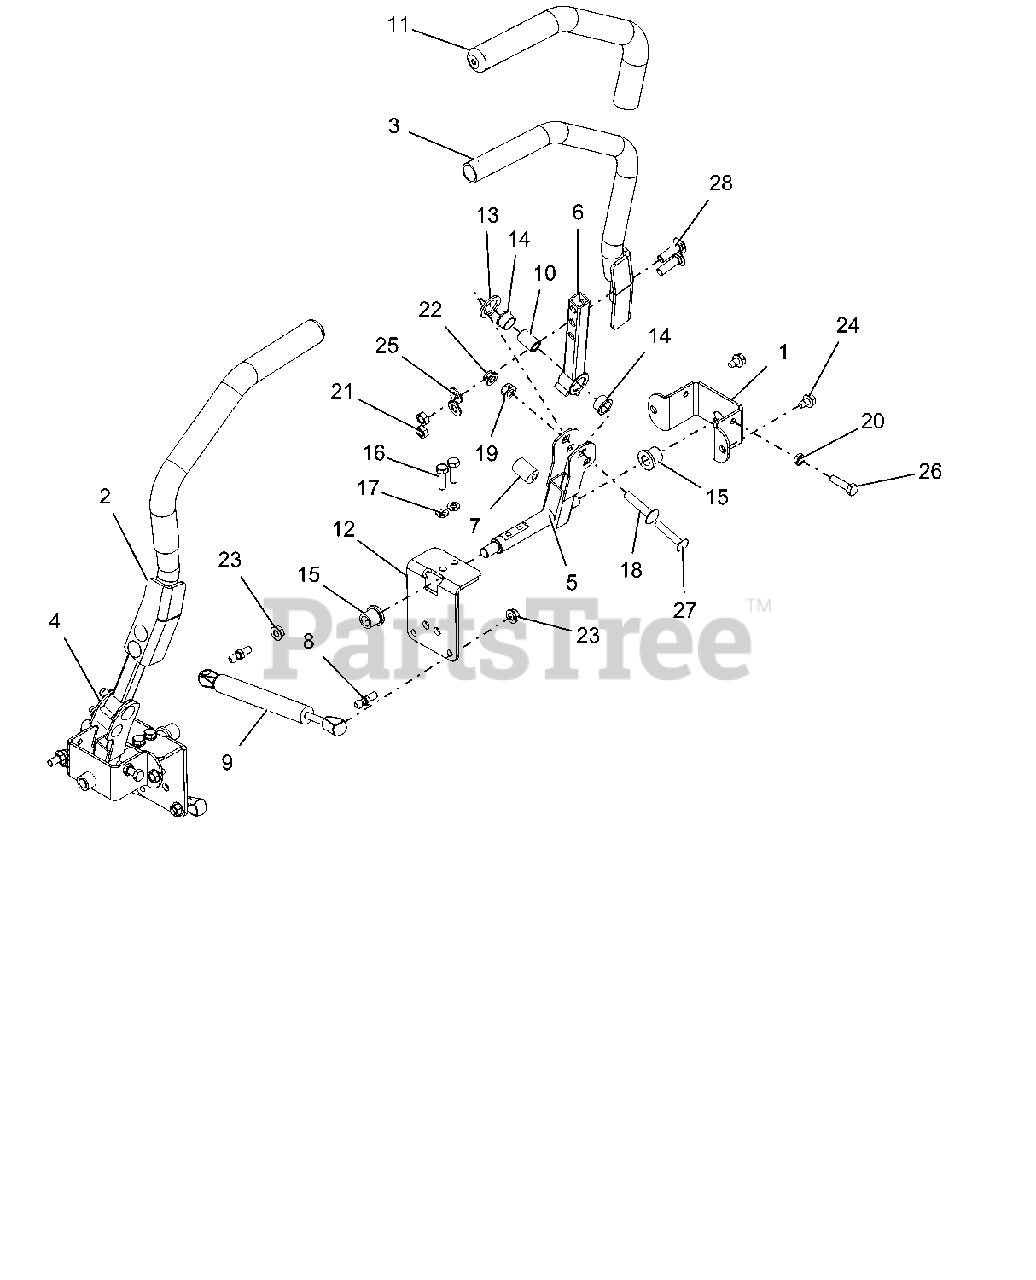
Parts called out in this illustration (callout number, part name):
1	BRKT, STEERING PIVOT (BLACK)
2	WLDMT, STEERING HANDLE RH
3	WLDMT, STEERING HANDLE LH
4	WLDMT, LOWER STEERING ARM
5	WLDMT, LOWER STEERING ARM-LH
6	WLDMT, UPPER CONTROL ARM (BLACK)
7	BSHG, SPCR .328X.750X1.01 PM
8	STUD-BALL
10	SPCR, .375X.625X.970
11	GRIP, HANDLEBAR 15" FOAM
12	BRKT, STEERING
13	WSHR, FRICTION .875X1.25X.10
14	BSHG, .625X.75X.450X.875
15	BSHG, FLANGE .515 X .750 X .745 X 1.00 NYLON
16	BLT-HEX .31-18X1.00 GR8 YWZC
17	WSHR-LK .31X.078 REG YWZC
18	BLT-RHDSSQNK .38-16X1.75 G5YZ
19	NUT, LK-CTR-FLG .38-16 YWZC
20	NUT, JAM .312-18 YWZC
21	NUT-LK-CTR-JAM .375-16 YWZC
22	NUT-LK-NYL-FLG .31-18 YWZC
23	NUT, LK-TOP-FLG .312-18 YWZC
24	SCR-TAP .31-18X.50 HWH TR YWZ
25	WSHR-FL-STL.406X.812X.065 YWZ
26	BLT-HEX .31-18X1.25 GR5 YWZC
27	BLT-RDHDSQSHNK .31-18X1.75 YWZC
28	BLT-RHDSSQNK .38-16X1.25 G5YZ
